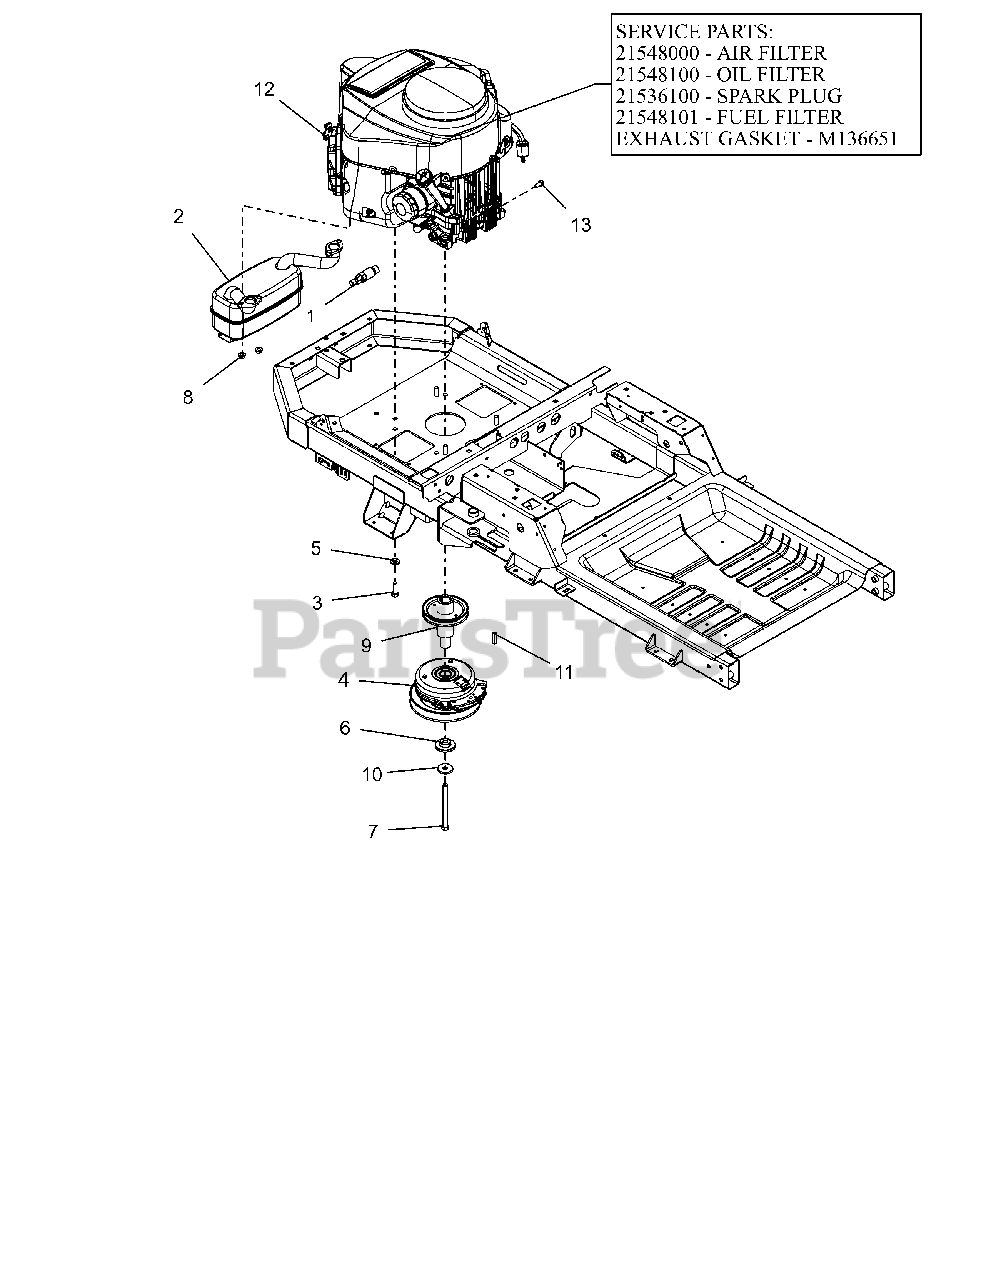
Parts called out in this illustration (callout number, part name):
1	DRAIN, OIL M20X2.5
2	MUFFLER - KAWASAKI
3	BLT, HEX .38-16X1.25 G5 ZCC NT
4	CLUTCH,105FTLB MONOPOLE 6.83"
5	WASHER, 3/8" SPRING DISC
6	BSHG-FLG .469X1.06X.574X2.0
7	BLT-HEX.438-20X5 GR8 YZ NYTORQ
8	NUT-LK-TOP-FLG M8 ZCC
9	WLDMT, DRIVE SHEAVE (LG XL)CZC
10	WASHER, 7/16" SPRING DISK
11	KEY-SQ .25 X 1.25 X .25 SAE
12	ENGINE, KAWASAKI FR651V 21.5HP
12	AIR FILTER, KAWASAKI FR
12	OIL FILTER, KAWASAKI FR
12	PLUG, SPARK
12	FUEL FILTER-KAWASAKI FR
12	GASKET, MUFFLER #
13	BLT, HEX M8-1.25X20 G8.8 ZCC
